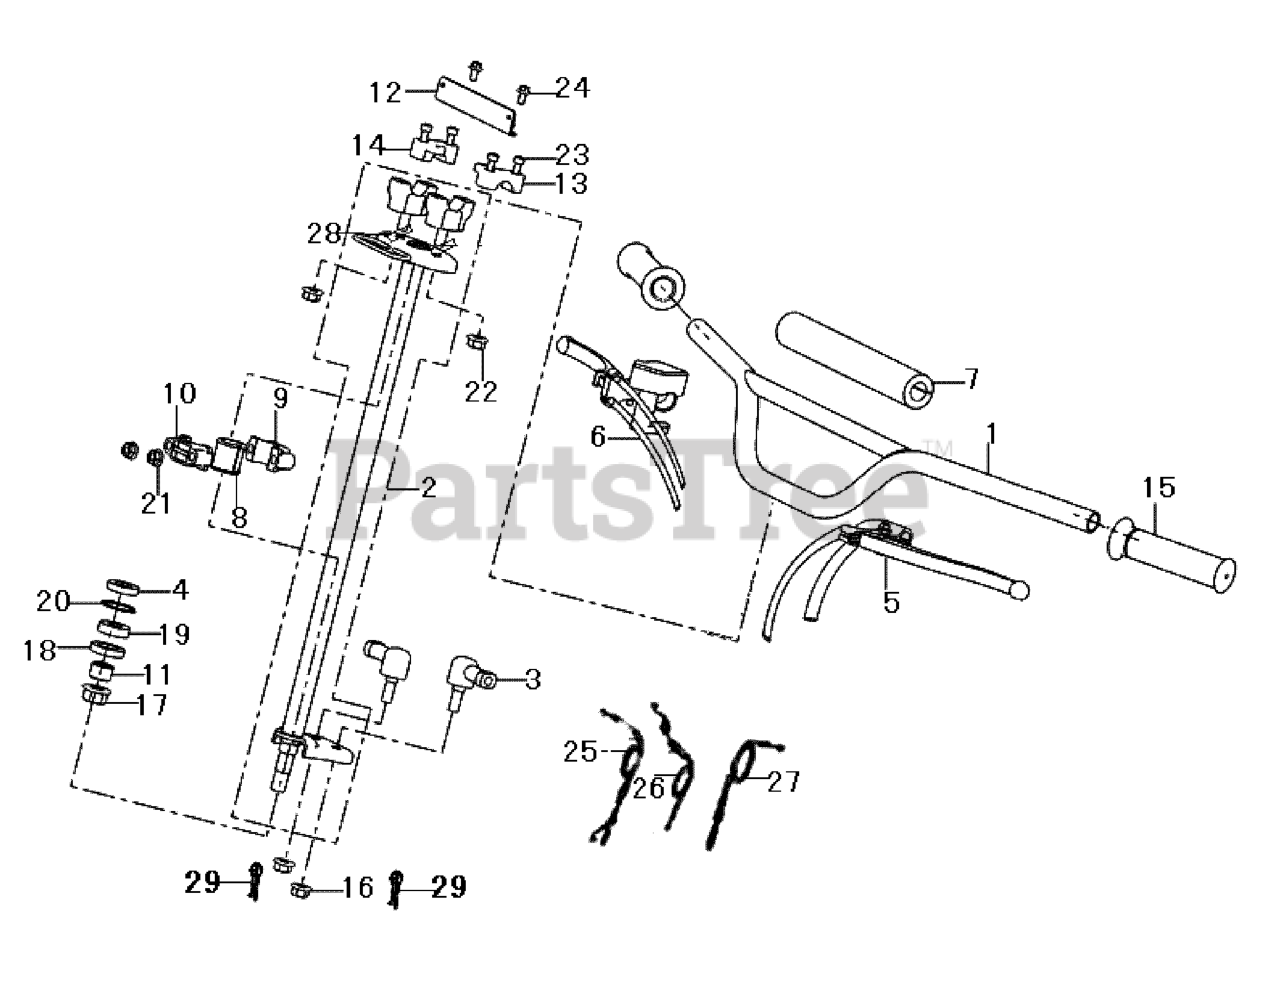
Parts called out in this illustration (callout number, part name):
1	HANDLEBAR
2	SHAFT, STEERING
3	BALL JOINT
4	SEAL, OIL
5	LEVER ASSY., LEFT
6	LEVER ASSY, RIGHT
7	PAD, HANDLEBAR
8	BUSHING, STEERING
9	COLLAR HALF, REAR BUSHING
10	COLLAR HALF, FRONT BUSHING
11	COLLAR, STEERING SHAFT
12	BRACKET
13	HANDLEBAR HOLDER, LEFT
14	HANDLEBAR HOLDER, RIGHT
15	GRIP, HANDLEBAR
18	OIL SEAL
19	BEARING
20	CIRCLIP
25	CABLE ASSY. 50cc, THROTTLE
26	CABLE ASSY., REAR BRAKE
27	CABLE ASSY., FRONT BRAKE
28	HANDLEBAR HOLDER (BOTTOM)
29	PIN, COTTER
